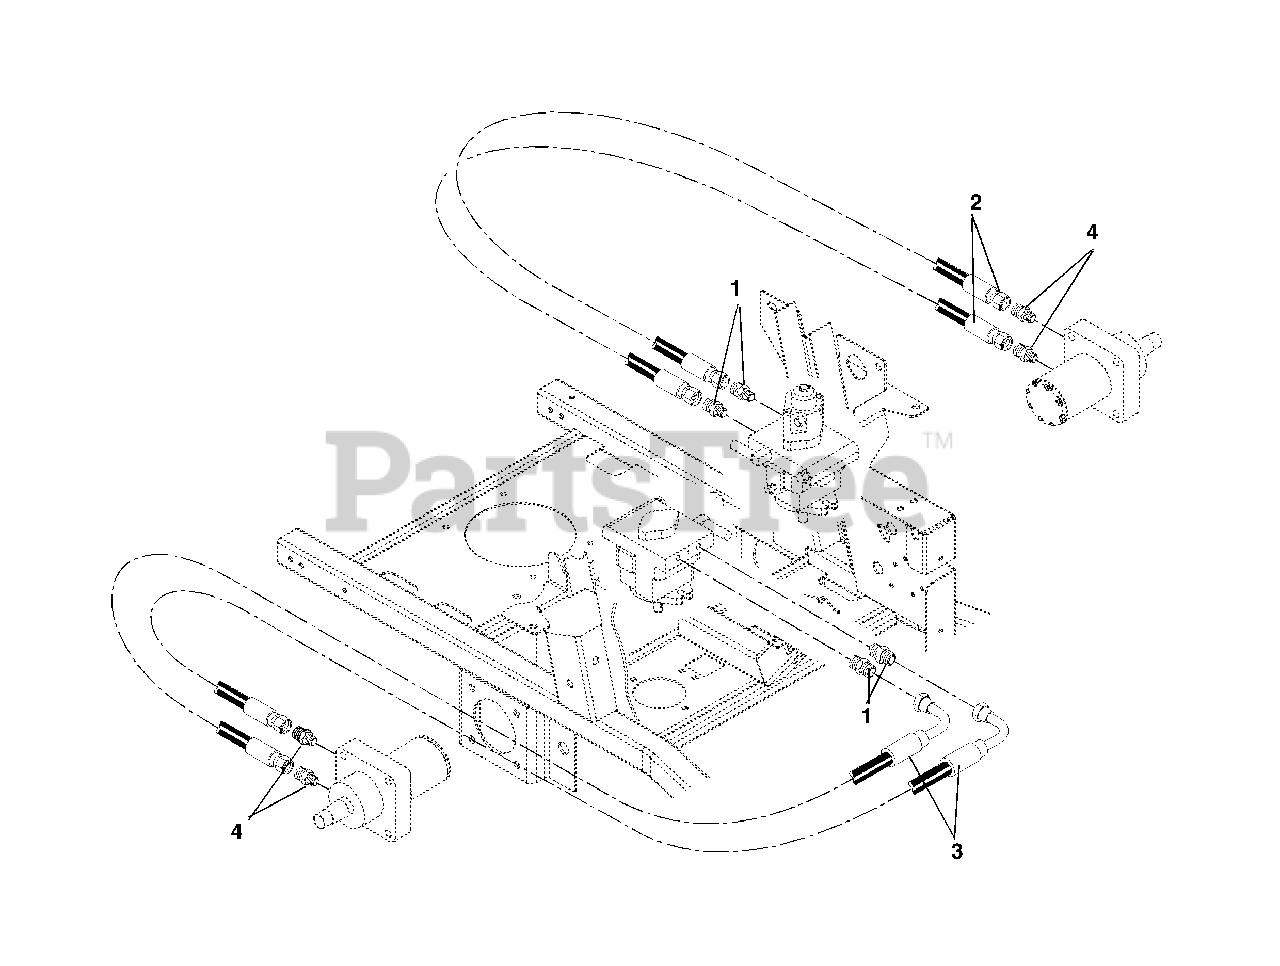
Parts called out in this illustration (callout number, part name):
1	Adapter-Hydraulic Steel .75 to .75
2	Hose-Hydraulic .50 18.75 Long
3	Hose-Hydraulic .50 x 29.50 Long
4	Adapter-Hydraulic Steel .875 to .75
